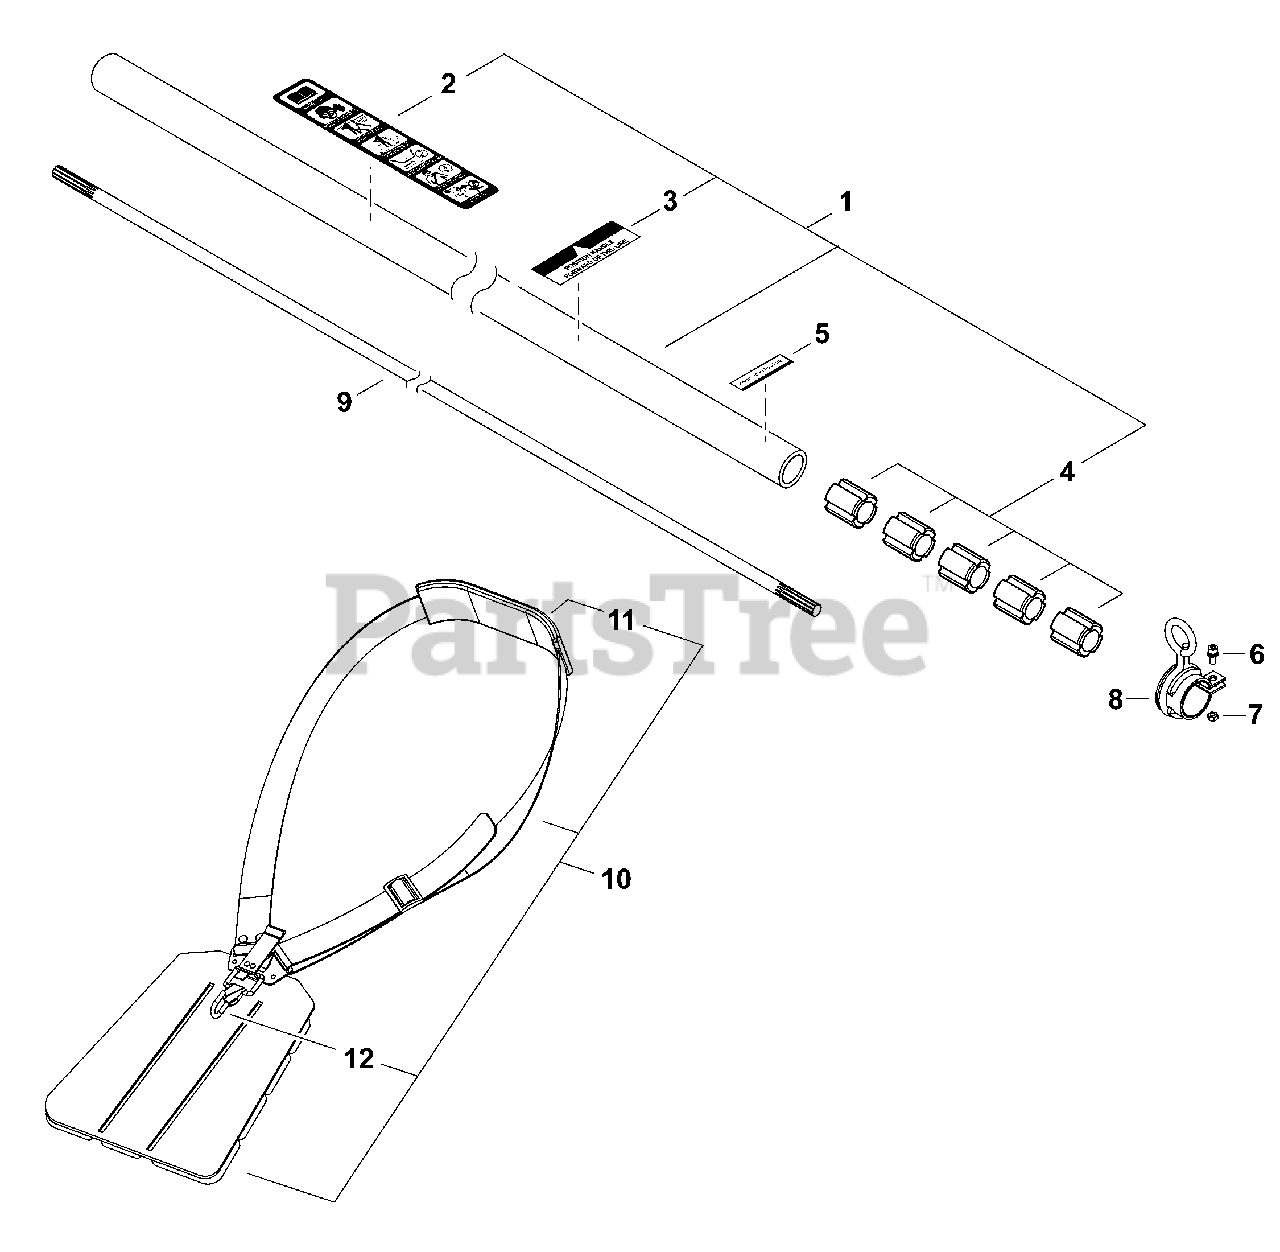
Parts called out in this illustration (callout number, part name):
1	MAIN PIPE ASSY
2	LABEL, CAUTION (BLADE CAPABLE)
3	LABEL - ALIGNMENT
4	BUSHING
5	LABEL - ALIGNMENT
6	BOLT 5
7	NUT - 5
8	HANGER, SWIVEL
9	MAINSHAFT
10	HARNESS ASSY, BRUSHCUTTER
11	PAD, SHOULDER
12	HOOK, SNAP
